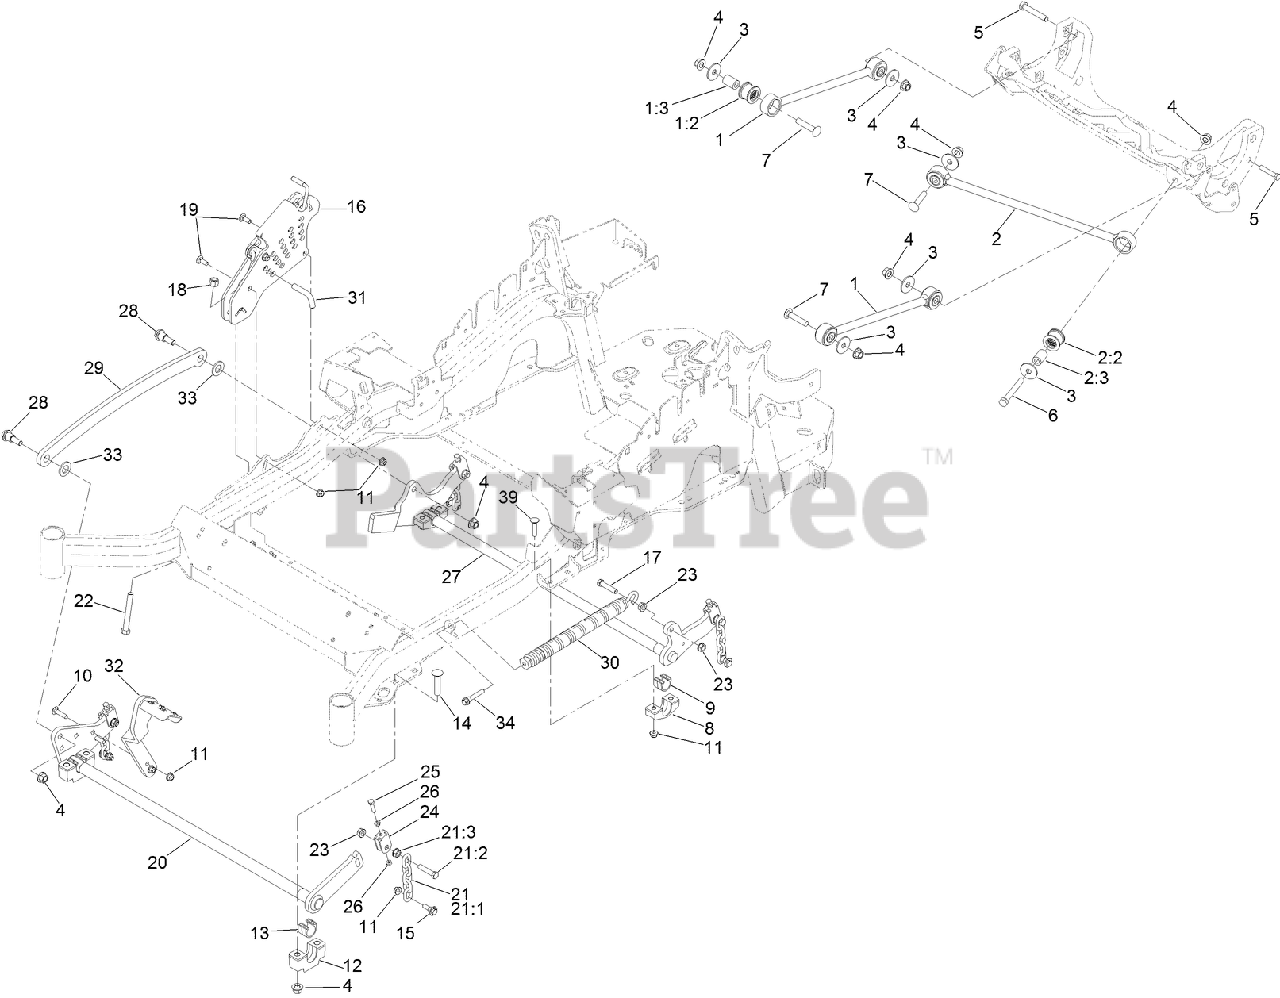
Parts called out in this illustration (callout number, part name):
1	DECK STRUT ASM
1:2	BUSHING-SUSPENSION, RUBBER
1:3	SPACER
2	PANHARD ROD ASM
2:2	BUSHING-SUSPENSION, RUBBER
2:3	SPACER
3	WASHER-THRUST
4	NUT-LOCK
5	SCREW-HH
6	SCREW-HH
7	SCREW-CARR
8	SUPPORT-CROSS SHAFT, BEARING REAR
9	BEARING-CROSS SHAFT, REAR
10	SCREW-HH
11	NUT-HF, NI
12	SUPPORT-CROSS SHAFT, BEARING
13	BEARING-CROSS SHAFT, FRONT
14	BOLT-CARR
15	SCREW-SHOULDER, HHF
16	HOC ASM
17	SCREW-HH
18	NUT-LOCK, NI
19	SCREW-HH
20	DECKLIFT-FRONT
21	DECK LIFT CHAIN ASM
21:1	CHAIN-LIFT, DECK
21:2	SCREW-HH
21:3	NUT-HF
22	BOLT-TAP
23	NUT-HF
24	YOKE-ADJUST, DECK
25	SCREW-HH
26	NUT-JAM
27	LIFT-DECK, REAR
28	SCREW-SHOULDER, HHF
29	LINK-LIFT, DECK
30	SPRING-EXTENSION
31	PIN-HOC
32	LEVER-FOOT
33	WASHER-FLAT
34	BOLT-SHOULDER
39	SCREW-HH
